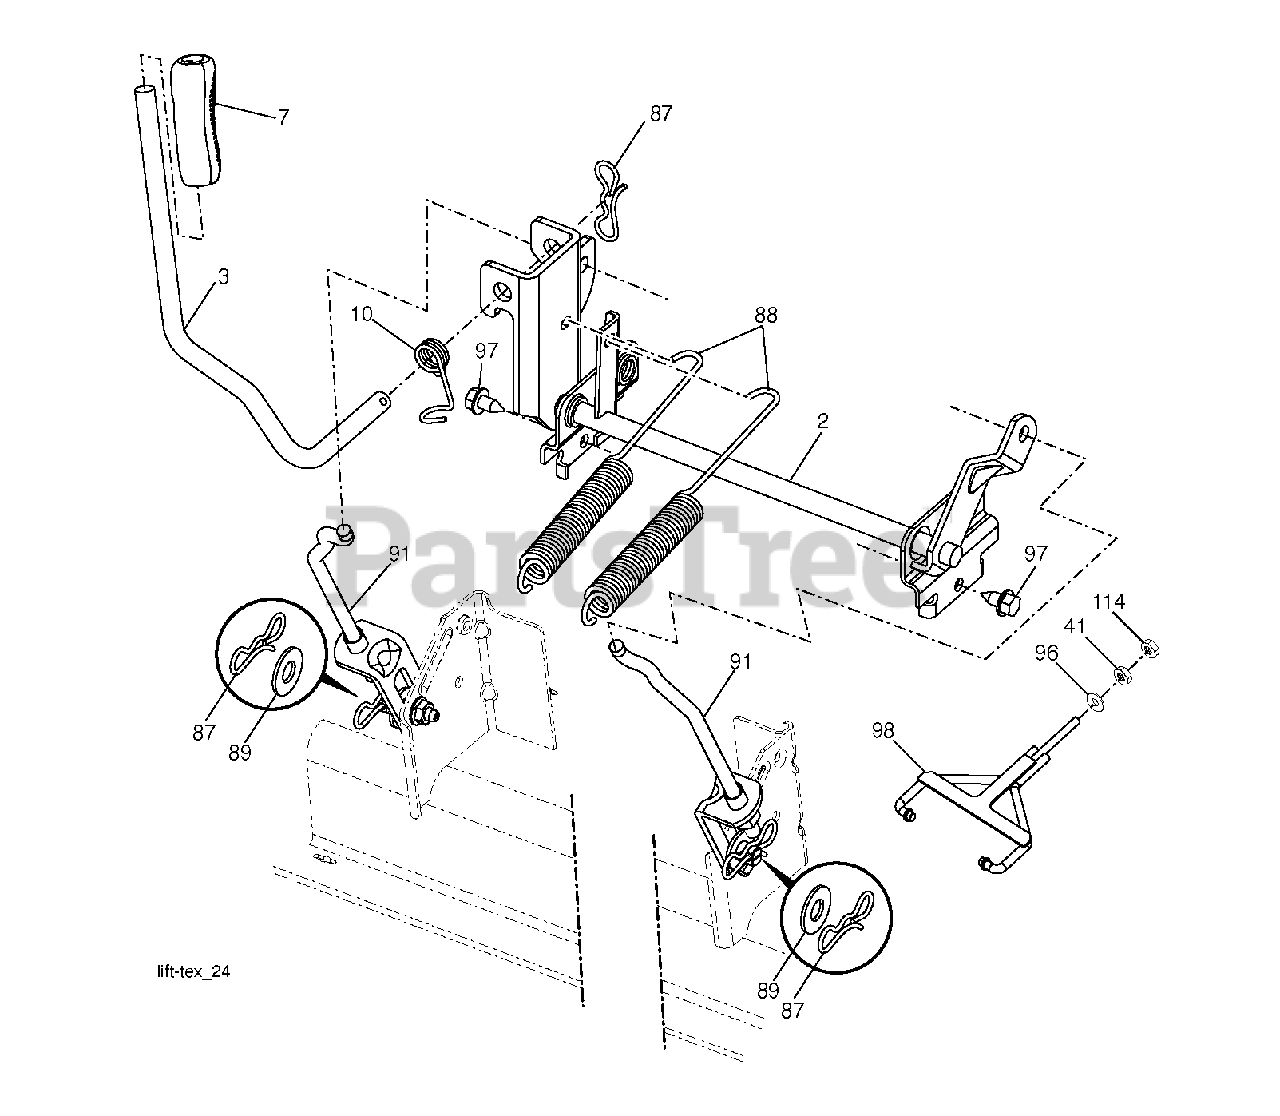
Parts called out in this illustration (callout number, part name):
2	ARM.LIFT.SHAFT.CROSS
3	LEVER.LIFT.HANDLE.GT
7	GRIP.HANDLE.LIFT.PVC.BLACK
10	SPRING.TORSION.LIFT.HANDLE
41	NUT, LIFT LINK 7/16-20
87	PIN.COTTER.7/16.BOW TI.
88	SPRING.LIFT.ASSIST
89	WASHER.CLEAR.ZINC
91	LINK.ASM.LIFT.54"TG
96	BUSHING SPHERICAL SUSP. FRONT
97	SCREW, 3/8-16X3/4
98	SUSPENSION WLDT FRONT DECK
114	NUT **
